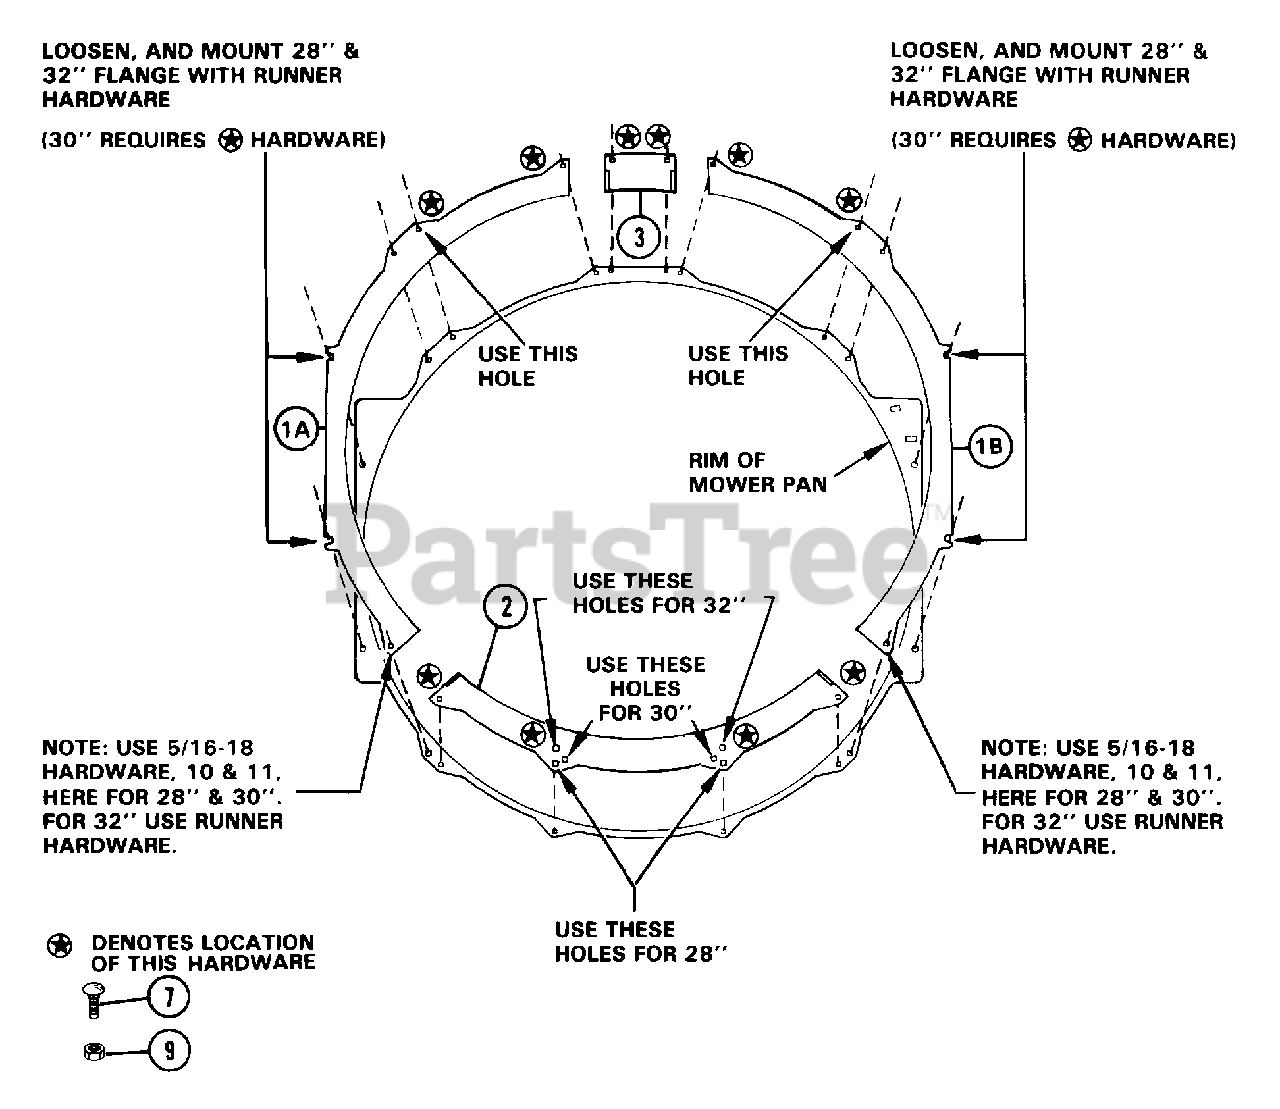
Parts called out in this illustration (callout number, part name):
1	28 IN SIDE FLANGE
2	BACK FLANGE
3	FRONT CLAMP
7	BLT-RDHDSQNK .25-20X.62 PL
9	NUT-LK-CTR .250-20 PL
10	BLT-RDHDSQNK .312-18X.62SHTPL
11	NUT-LK .312-18 GR A PL
